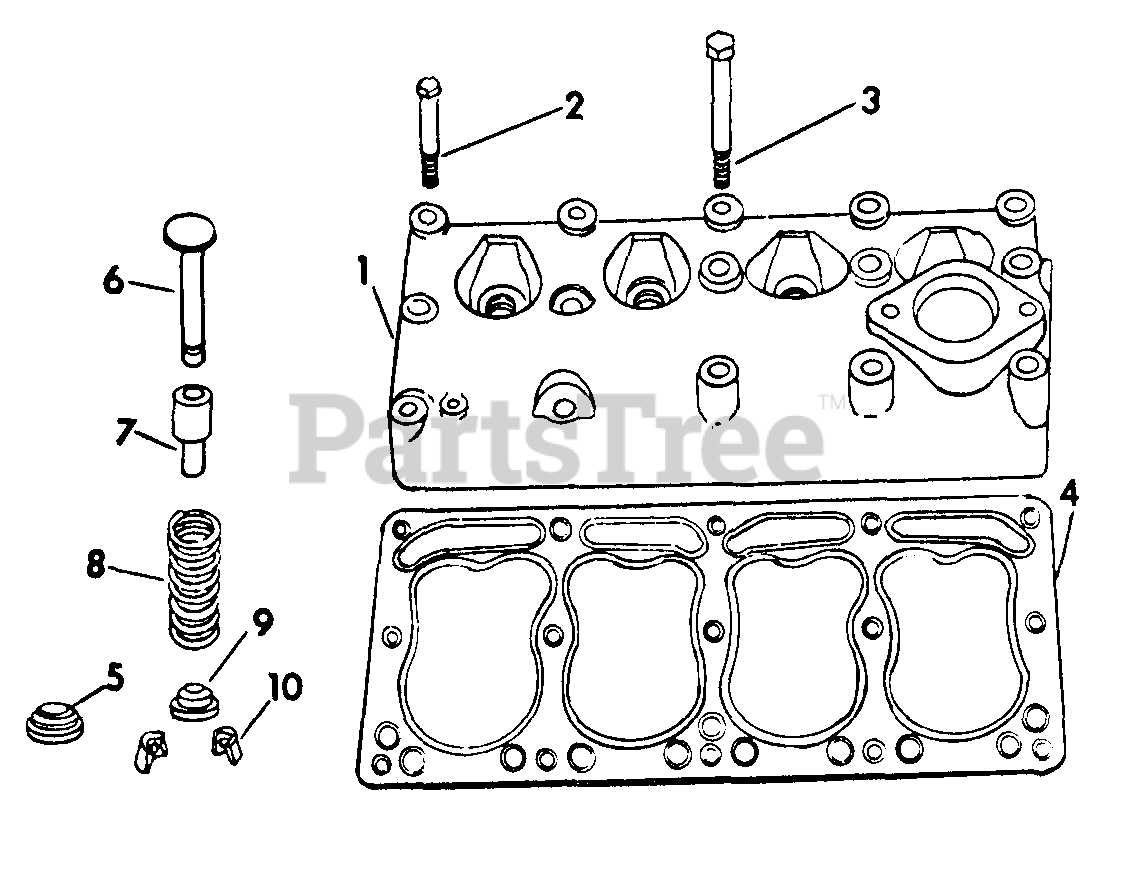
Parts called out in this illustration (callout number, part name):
1	HEAD, CYLINDER
2	SCREW, CYL HEAD SHORT CAP
3	SCREW, CYL HEAD LONG CAP
4	GASKET, CYLINDER HEAD
5	ROTOCAP, EXHAUST VALVE
6	VALVE, INTAKE
7	GUIDE, VALVE
8	SPRING, VALVE
9	SEAT, VALVE SPRING
10	KEY, VALVE SPRING SEAT
